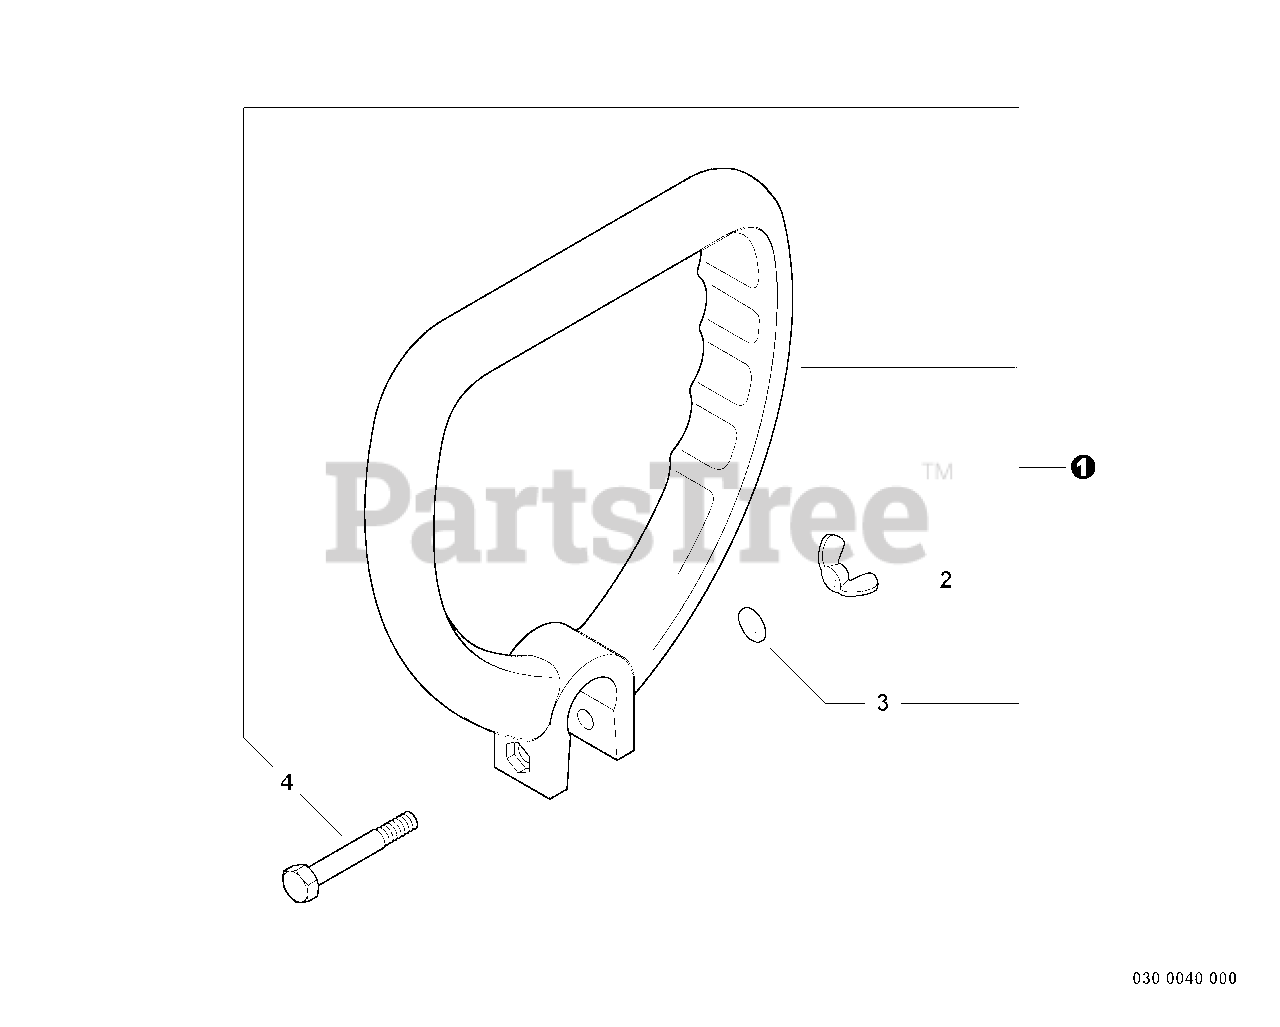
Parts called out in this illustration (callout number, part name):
1	HANDLE ASSY
2	NUT, WING 1/4"-20
3	WASHER, 1/4"
4	BOLT 1/4"-20×1-1/2"
